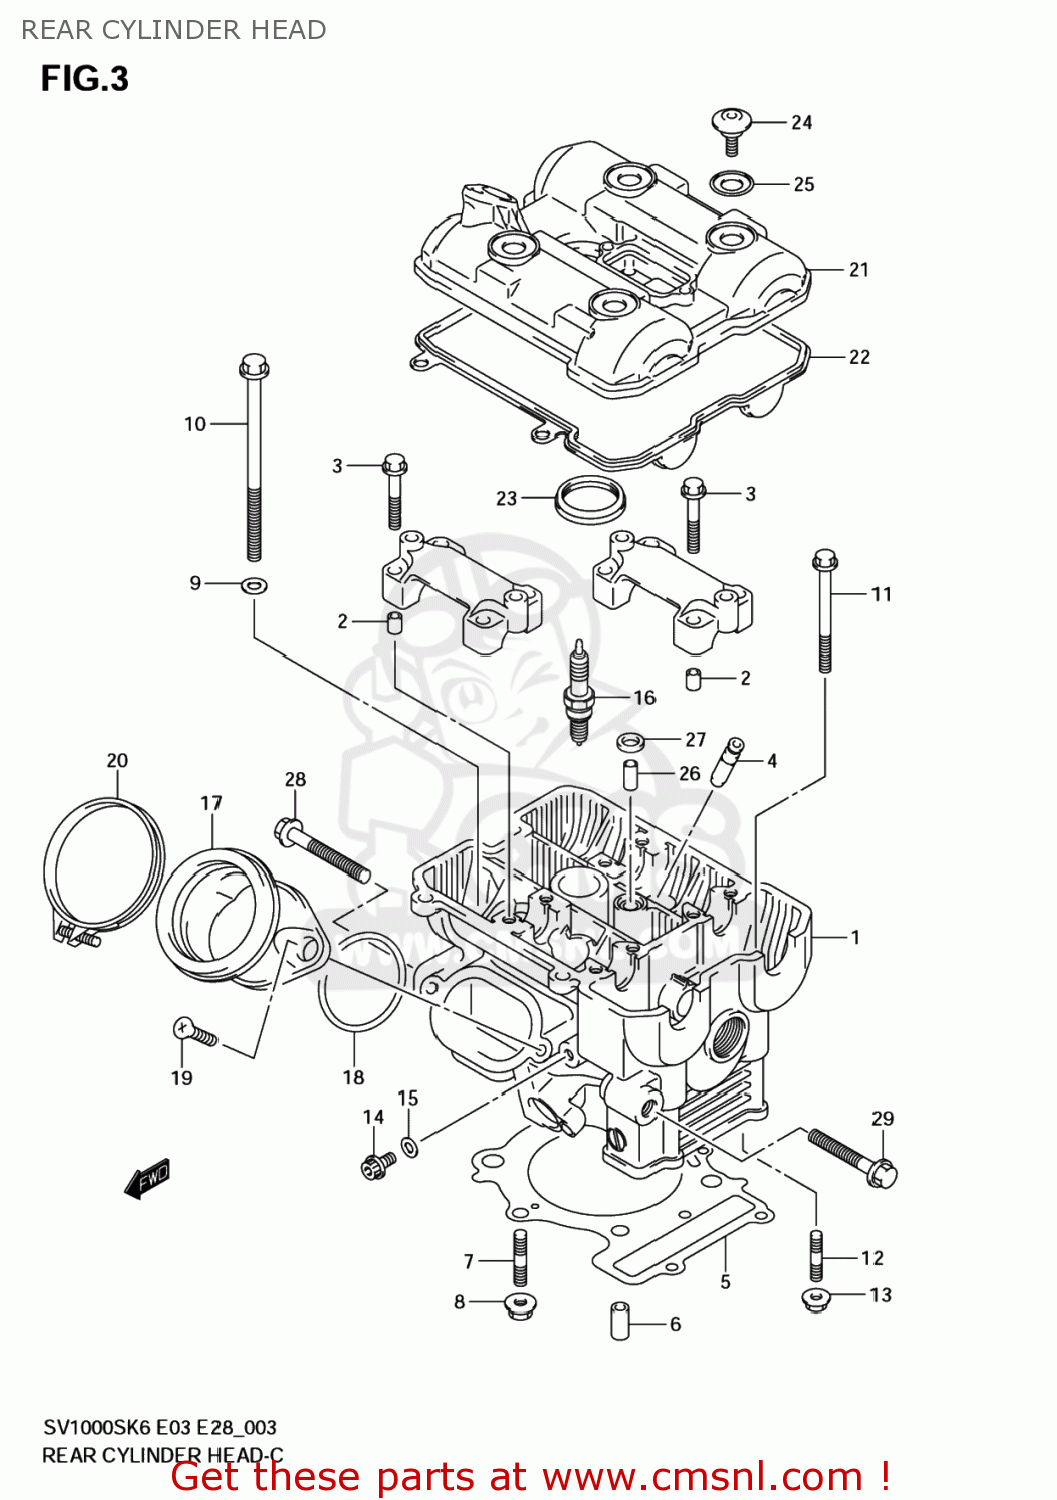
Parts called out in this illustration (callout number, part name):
1	HEAD ASSY,CYLINDER FR
2	PIN(6.2X8X11)
3	BOLT(6X39)
4	GUIDE,VALVE
5	GASKET,CYLINDER HEAD (NAS)
6	PIN
7	BOLT,STUD
8	NUT
9	WASHER(10.5X19X2)
10	BOLT(10X175)
11	BOLT(6X70)
12	BOLT,STUD
13	NUT
14	BOLT
15	GASKET(5.8X13X1.2) (NAS)
16	PLUG,SPARK(CR8EK)
17	PIPE ASSY,INTAKE RR
18	O RING(D:2.4,ID:55.6)
19	SCREW ,6X16
20	CLAMP
21	COVER,CYLINDER HEAD RR
22	GASKET,CYL HEAD COVER NO.1 (NAS)
23	GASKET,CYL HEAD COVER NO.2
24	BOLT(7X17.5)
25	WASHER(10.6X25.5X2.3)
26	PIN(6.2X8X16)
27	GASKET,2ND AIR PASSAGE (NAS)
28	BOLT
29	BOLT
